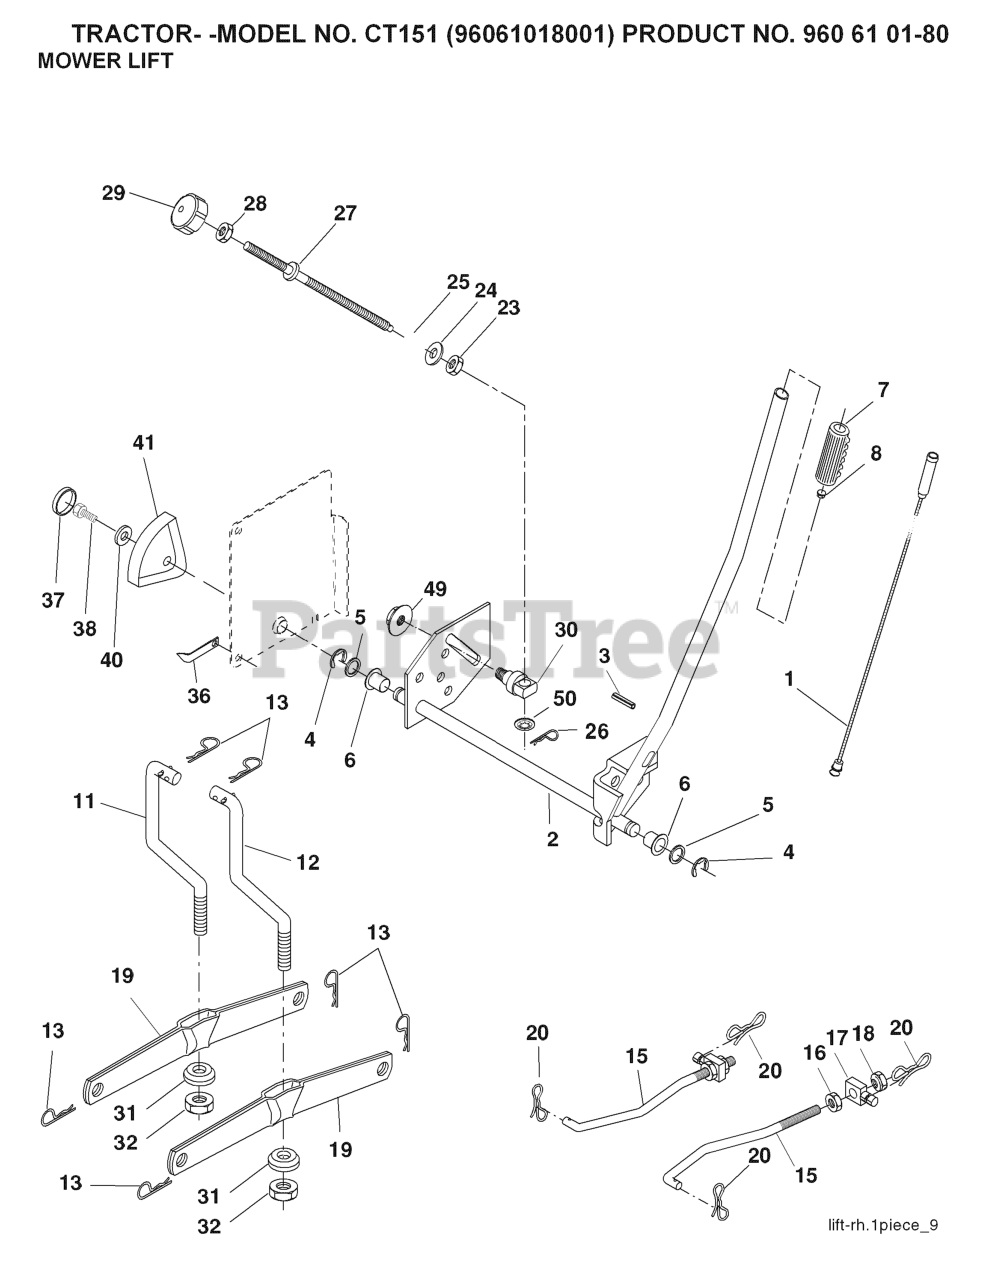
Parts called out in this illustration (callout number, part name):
1	WIRE ASM INNER W/ PLUNGER LT
2	SHAFT ASM R HANDLE
3	PIN GROOVE.
4	RETAINING RING LT
6	BEARING.NYLON
7	GRIP HANDLE
8	REPL BY 532 12 59-25
11	LINK
12	LINK
13	RETAINER-SPRNG RB
15	LINK.SUSPENSION.FRONT
16	NUT.HEX.JAM.1/2-13
18	NUT.LK.W/WSH.1/2.
19	ARM.REAR.SUSPENSION
20	PIN.COTTER.7/16.BOW TI.
26	RETAINER CLIP
27	ROD ADJ LIFT
28	NUT
29	KNOB INF 3/8-16
31	BEARING.PIVOT.LIFT
32	NUT CROWNLOCK 3/8-24
36	POINTER, HEIGHT INDICATOR(2 2)
38	SCREW 5/16-18X1
41	HEIGHT INDICATOR
49	NUT
50	NUT PUSH M
